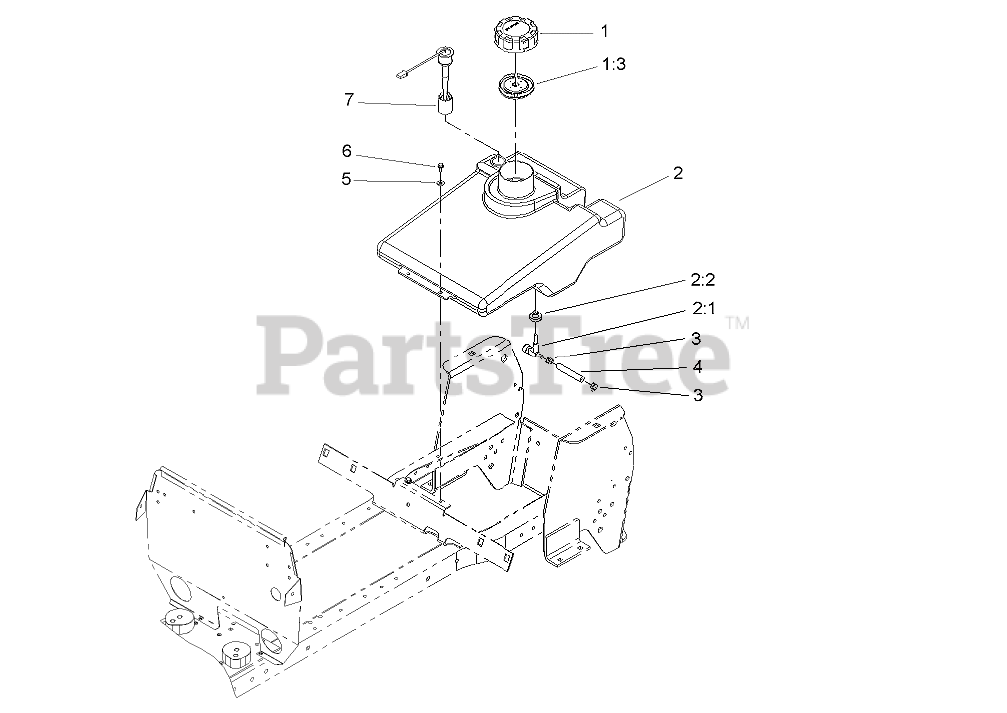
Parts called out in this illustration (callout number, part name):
1	GAS CAP ASM
1:3	GASKET-CAP, GAS
2	TANK-FUEL
2:1	VALVE-FUEL
2:2	BUSHING
3	CLAMP-HOSE
4	HOSE-LINE, FUEL
5	WASHER-FLAT
6	SCREW-HWH
7	SENSOR-FUEL, LOW
